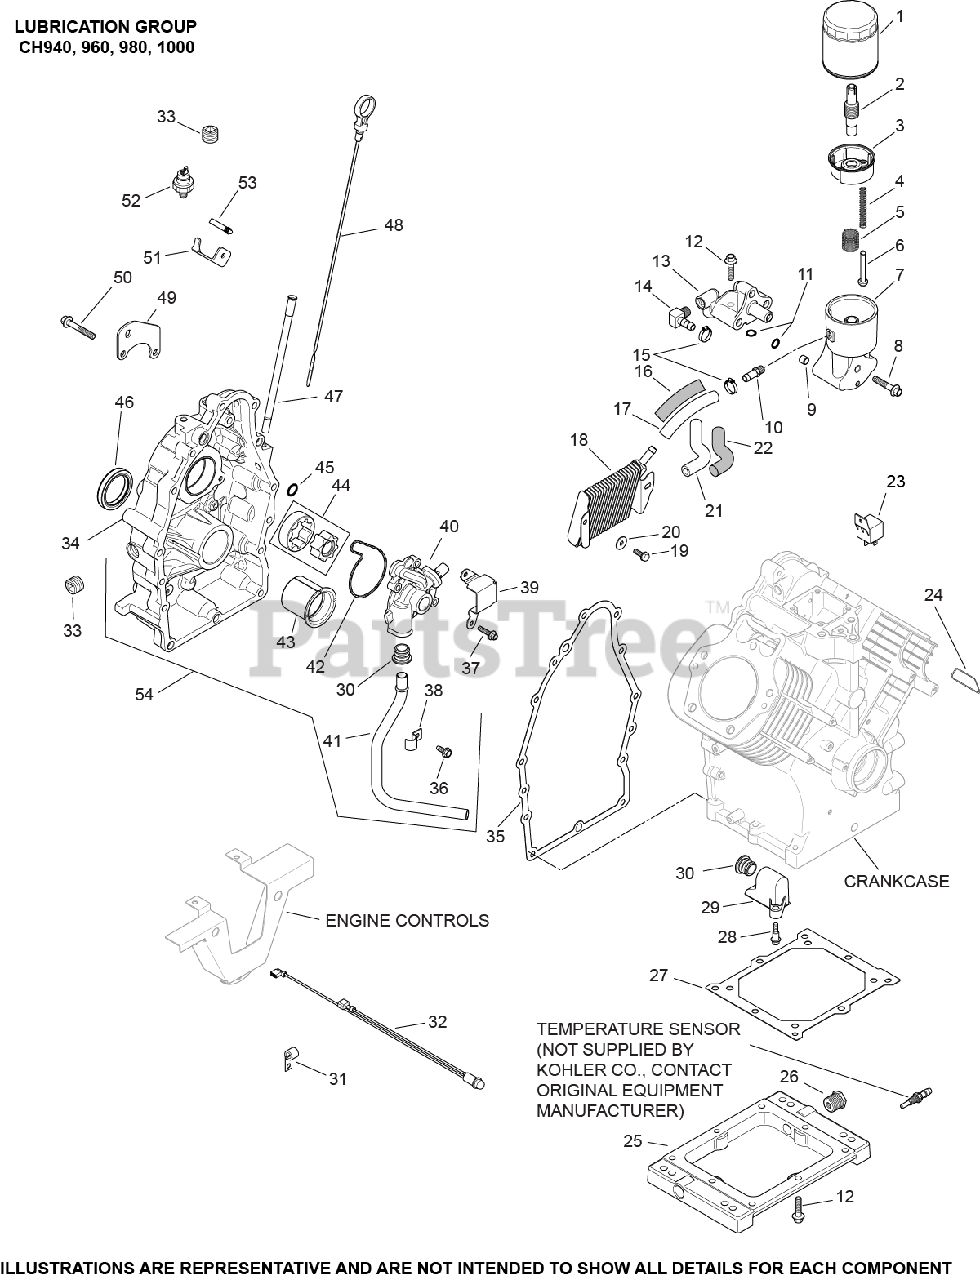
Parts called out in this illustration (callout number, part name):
1	OIL FILTER
2	NIPPLE, OIL FILTER ASSEMBLY
3	CUP, OIL FILTER ASSEMBLY
4	SPRING, OIL FILTER VALVE
5	SPRING, OIL FILTER CUP
6	VALVE, OIL FILTER
11	O-RING, OIL PICK-UP
12	SCREW, FLG M8X1.25X30
16	SLEEVE, ANTI ABRASION-USE 25 431 12-S
17	HOSE, OIL RETURN
18	COOLER, OIL ASSY - USE 62 594 03-S
19	SCREW, TAP M6X1.7X18
20	WASHER, FLAT 1/4"
21	HOSE, OIL SUPPLY
22	SLEEVE, ANTI ABRASION-USE 25 431 12-S
25	KIT, OIL RESERVOIR
27	GASKET, OIL RESERVOIR
28	SCREW, SHD THD FRM M6X.0X6.5
29	HOUSING, OIL PICK-UP ASSEMBLY
30	SEAL, PICK-UP TUBE
33	PLUG, PIPE 1/2 NPTF SQ CTSK
34	KIT, CLOSURE PLATE
35	GASKET, OIL PAN
36	SCREW, THREAD FORMING
41	TUBE, OIL PICK-UP
42	O-RING, OIL PUMP HOUSING
43	BEARING, CRANKSHAFT (PTO)
44	PUMP ASSEMBLY, OIL/GEROTOR
46	SEAL, OIL
47	KIT, DIPSTICK TUBE
49	STRAP, LIFTING
50	SCREW, FLG M8X1.25X50 USE 25 086 618-S
51	BRACKET, DIPSTICK TUBE
52	SWITCH, OIL PRESSURE
2513960-S	PLUG, CTSK PIPE 1/8"
6208134-S	KIT, OIL FILTER HOUSING
